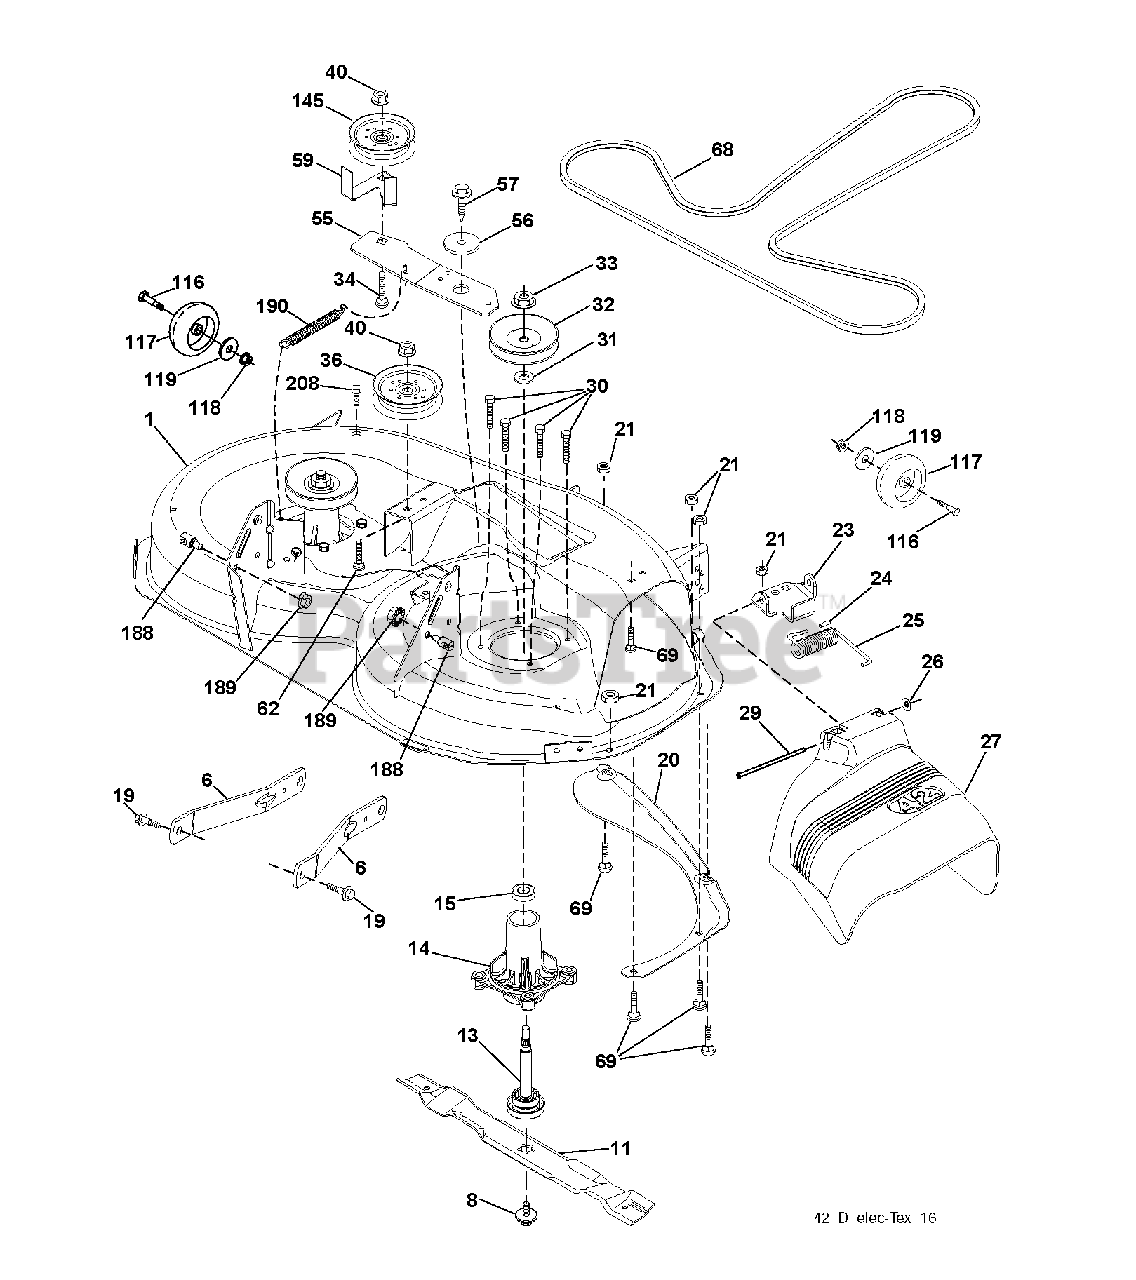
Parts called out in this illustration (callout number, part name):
1	DECK.WELDMENT.42"
6	ARM.SUSPENSION.MOWER.R
8	BOLT.WASHER.ASM.7/16-2
11	42" HI-LIFT BLADE
13	SHAFT.ASM.MDRL.N/GREASE.38
14	HOUSING MANDREL
19	BOLT.SHOULDER
20	BAFFLE.VORTEX
21	LOCKNUT
23	BRKT.DEFLECTOR.38"2005+
24	CAP-SLEEVE LT
25	SPRING.TORSION.DEFLECT
26	NUT PUSH M
27	SHIELD.DEFLECTOR.MOWER.42"BLAC
29	ROD.HINGE
30	SCREW, WASHER HEAD
31	WASHER.SPACER.MANDREL
32	PULLEY/MANDREL
33	NUT.FLANGE.LOCK.TOP
34	BOLT.3/8-16X1.50
36	PULLEY.IDLER.2006
40	NUT LOCK FLG 3/8-16 UNC
55	IDLER.ARM
56	SPACER.RETAINER
57	SCREW 3/8-16X1
59	GUARD, BELT
62	BOLT
68	BELT V SECONDARY
69	BOLT
117	WHEEL.GAGE.HALF.SPOKED
118	LOCKNUT
119	WASHER
145	PULLEY.IDLER.48"PRIMARY
188	STUD.FASTNER.W/ANTI-ROTATE
189	NUT LOCK HEX FLANGE 5/16-18
190	SPRING.MOWER.DRIVE.ELECTRIC
208	SCREW 3/8-16X1/2
